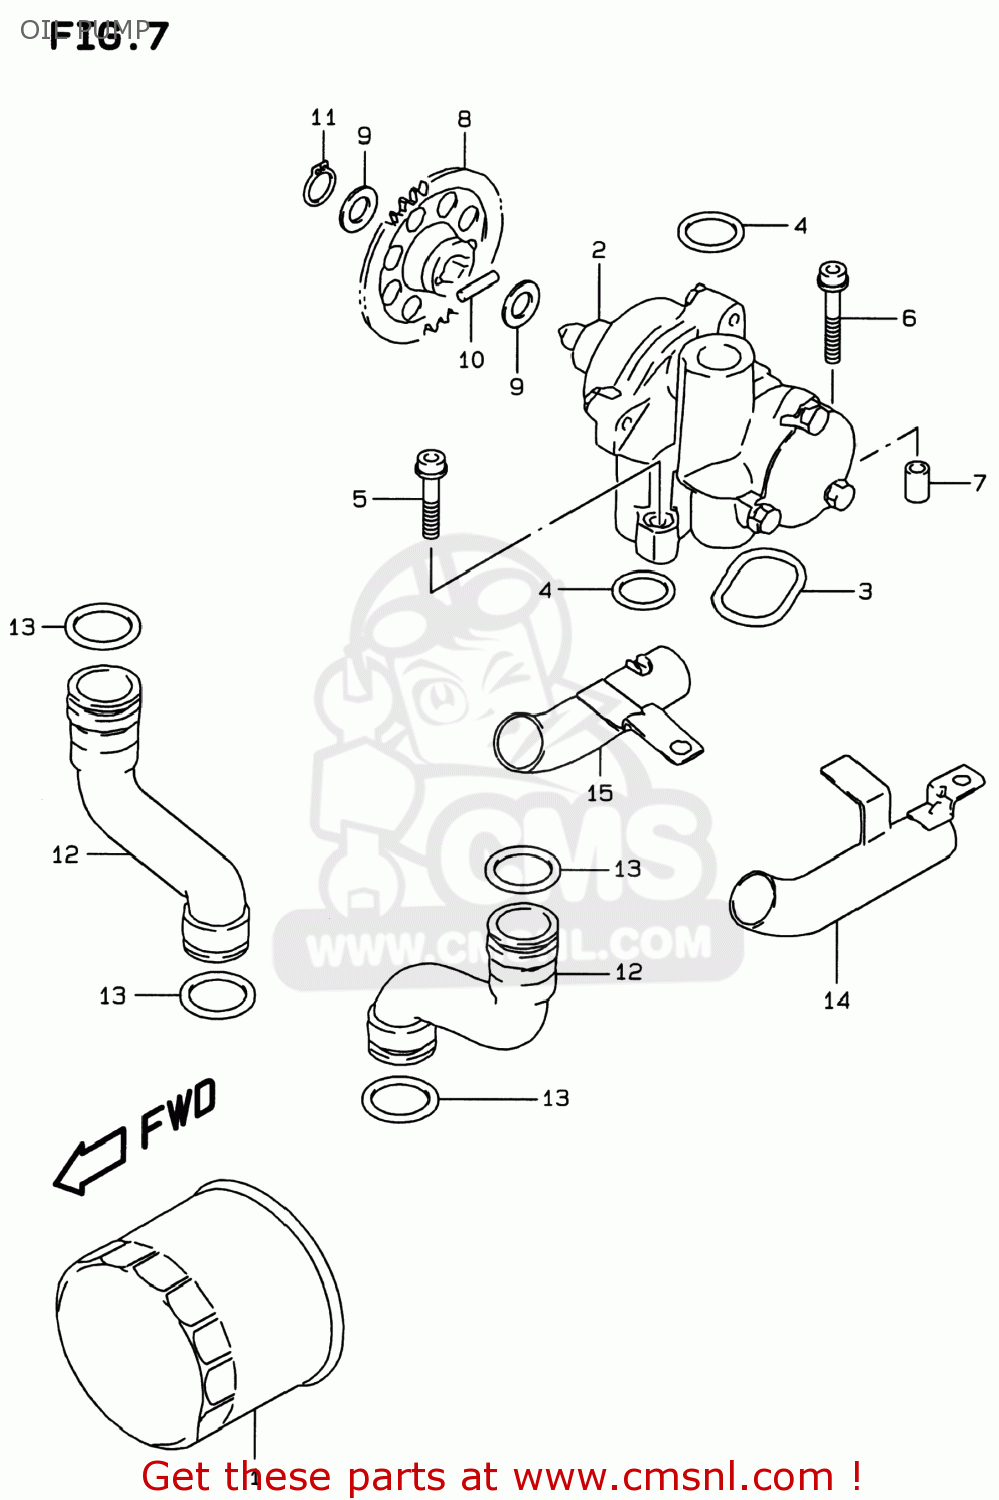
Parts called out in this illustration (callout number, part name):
1	FILTER ASSEMBLY,ENGINE OIL
2	PUMP ASSY,OIL
3	O RING,OIL PUMP
4	O RING(D:3.2,ID:17.8)
5	BOLT
6	BOLT
7	PIN
8	GEAR,OIL PUMP DRIVEN(NT:37)
9	SHIM
10	PIN(5X18)
11	CIRCLIP,12 MM
12	PIPE,OIL OUTLET
13	O RING(D:3.7,ID:21.7)
14	PIPE,OIL OUTLET UNDER,L
15	PIPE,OIL OUTLET UNDER,R
